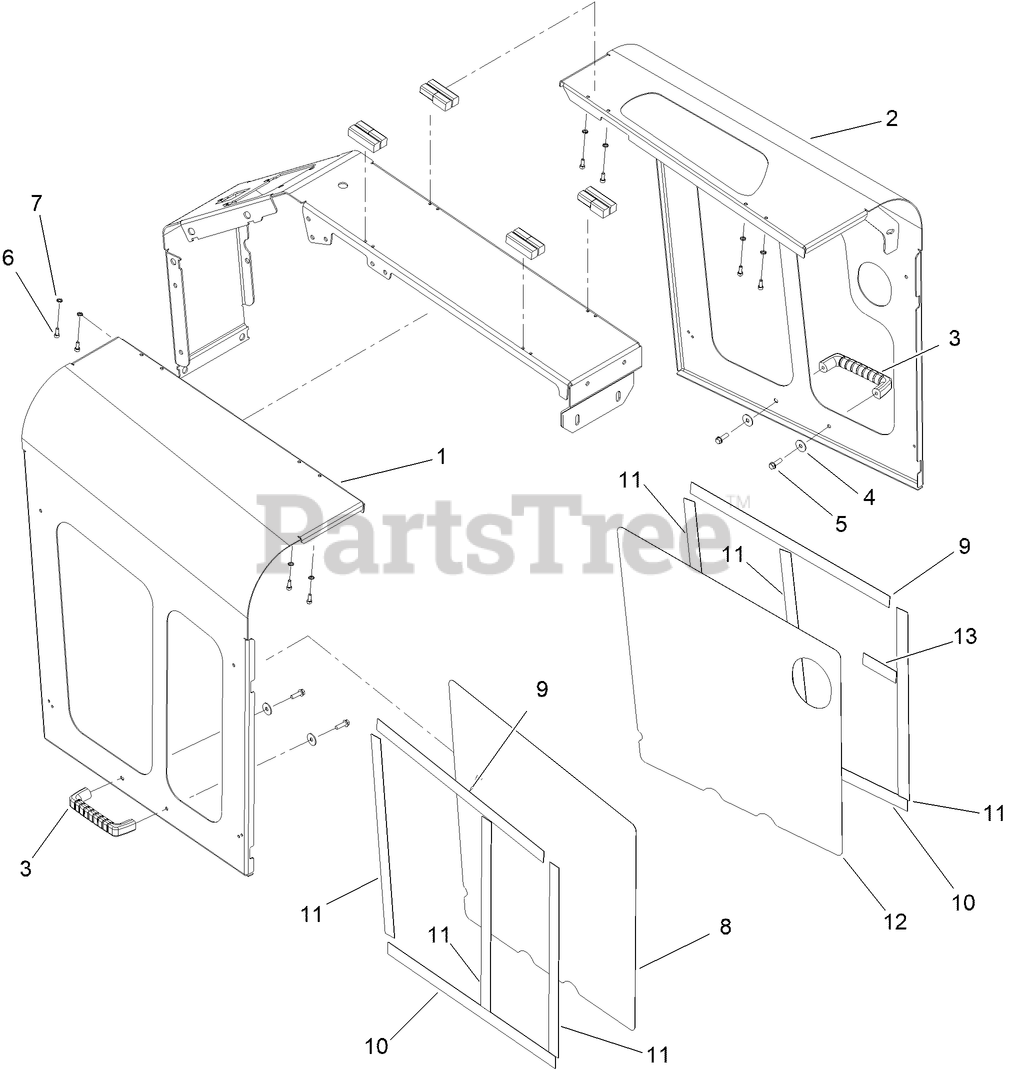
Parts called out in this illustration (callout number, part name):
1	HOOD-RIGHT (TORO RED)
2	HOOD-LEFT (TORO RED)
3	HANDLE-DOOR
4	WASHER-PLAIN
5	SCREW-HWH
6	SCREW -HSH
7	WASHER-LOCK, EXT
8	SCREEN-RIGHT SIDE
9	VHB TAPE (1.0") HIGH ENERGY
10	VHB TAPE (1.0") HIGH ENERGY
11	VHB TAPE (1.0") HIGH ENERGY
12	LEFT DOOR SCREEN
13	VHB TAPE (1.0") HIGH ENERGY
